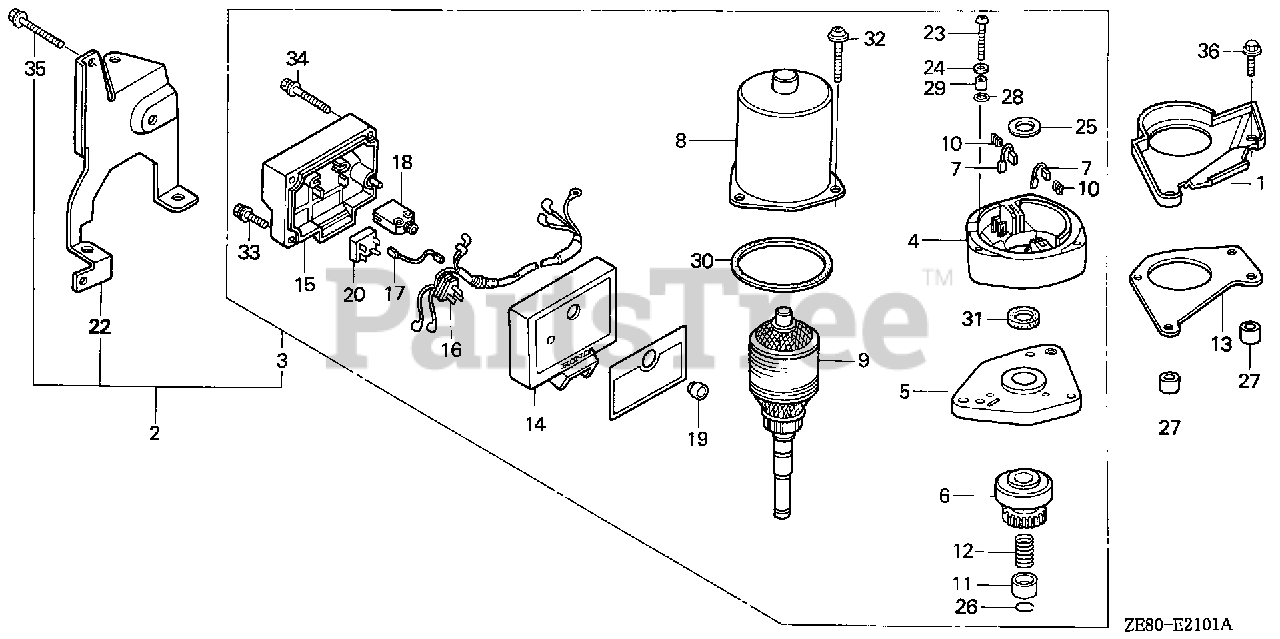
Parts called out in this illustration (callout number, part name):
1	PLATE, SIDE
2	STARTER MOTOR ASSY. (NOT AVAILABLE)
3	STARTER MOTOR ASSY. (NOT AVAILABLE)
4	HOUSING, CENTER
5	HOUSING, PINION
9	ARMATURE (NOT AVAILABLE)
10	SPRING, BRUSH RETURN
11	STOPPER, PINION
12	SPRING, COIL
13	BRACKET, STARTER MOTOR
18	SWITCH, STARTER (A.C. 380V/16A)
18	SWITCH, STARTER (A.C. 250V/16A)
22	BRACKET, SWITCH BOX
23	SCREW, TRUSS (4X30)
24	WASHER, STAR (4MM)
26	RING, RETAINING
27	PIN A, DOWEL (10X14)
32	SCREW-WASHER (5X40)
33	SCREW-WASHER (4X20)
34	SCREW-WASHER (4X30)
35	BOLT, FLANGE (6X40)
36	BOLT, FLANGE (8X28)
